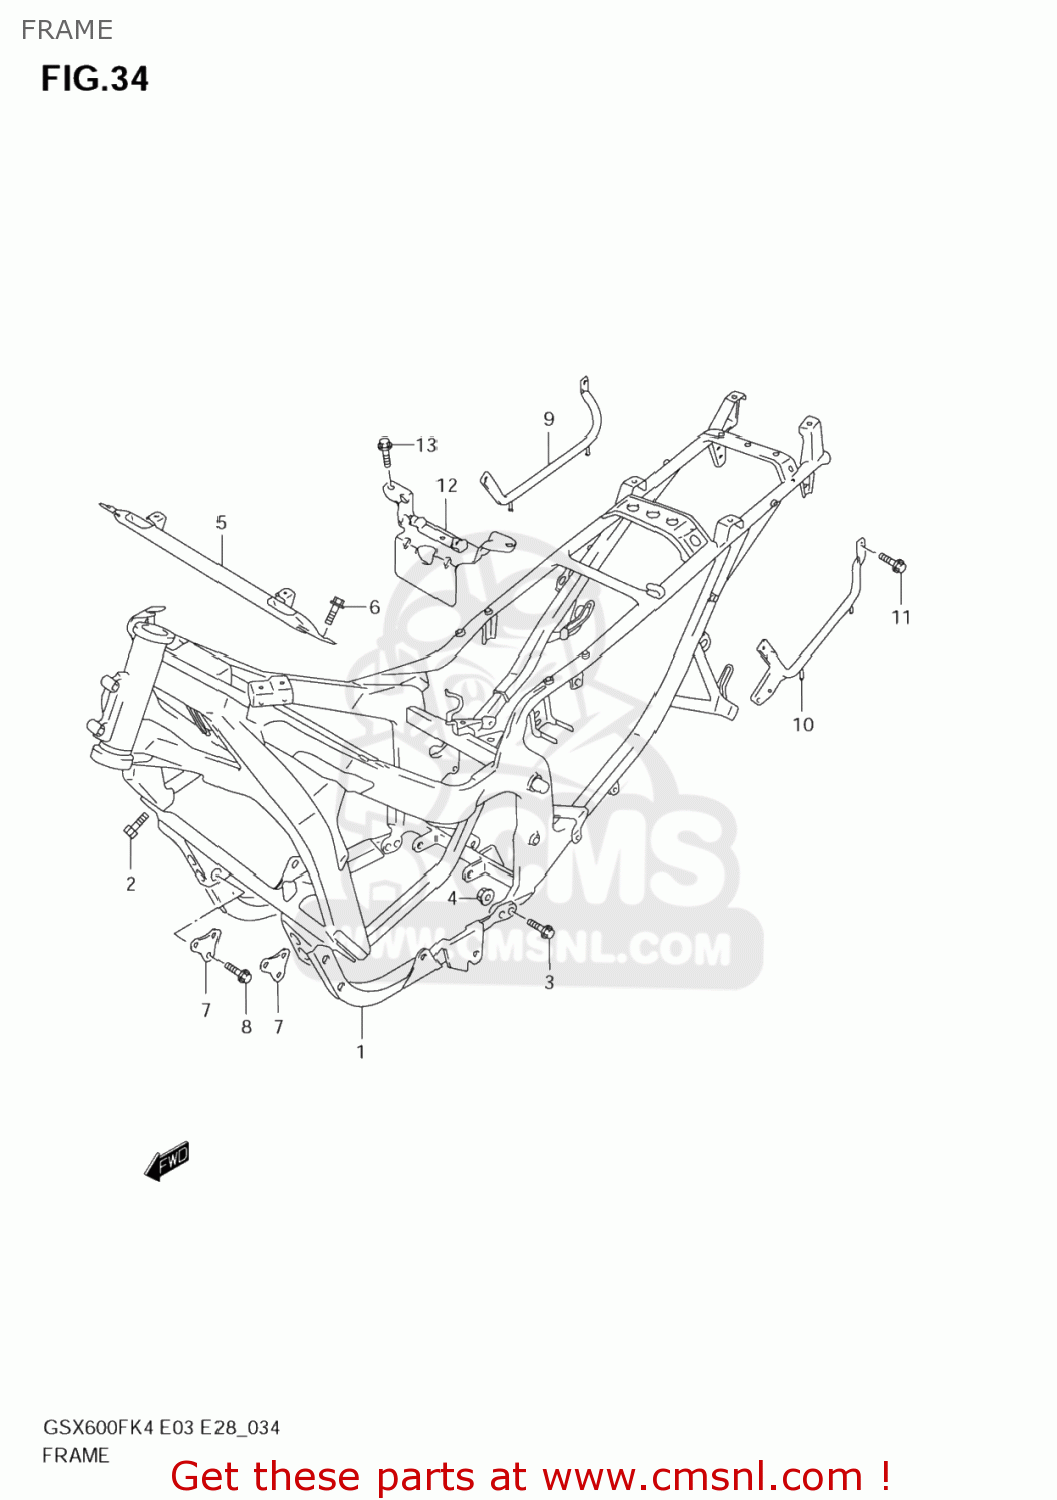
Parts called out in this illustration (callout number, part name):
1	FRAME(BLACK)
2	BOLT
3	BOLT
4	NUT
5	TUBE,FRAME BRIDGE NO.2
6	BOLT(8X20)
7	PLATE,ENG MTG NO.1
8	BOLT, UPPER
9	GRIP,RR,R
10	GRIP,RR,L
11	BOLT
12	PLATE,ELECTRIC PARTS HOLDER
13	BOLT
